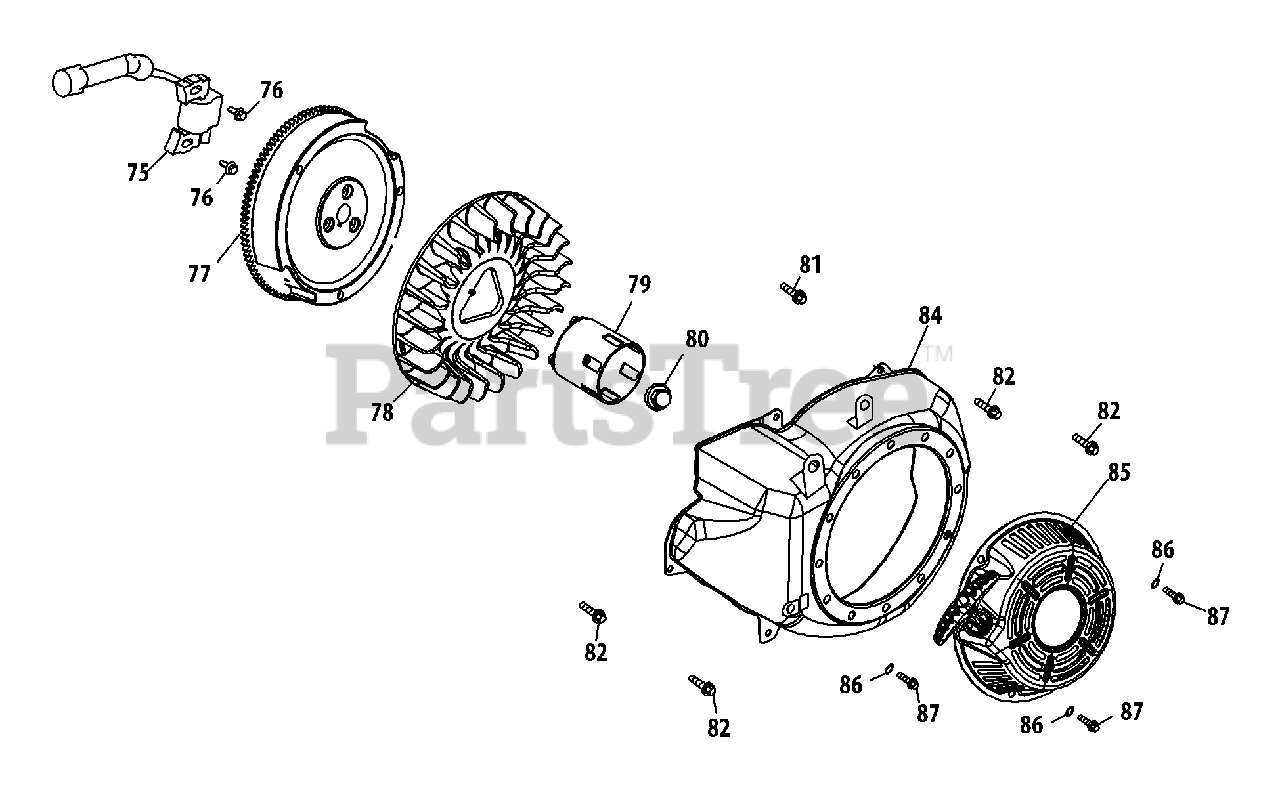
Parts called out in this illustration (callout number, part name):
75	Ignition Coil Assembly
76	Ignition Coil Bolt
78	Fan, Cooling
79	Pulley, Starter
80	Nut, Special, M16×1.5
81	Bolt M6×16
82	Bolt M6×12
84	Starter Housing
85	Recoil Starter
86	Gasket 6
87	Bolt M6×10
